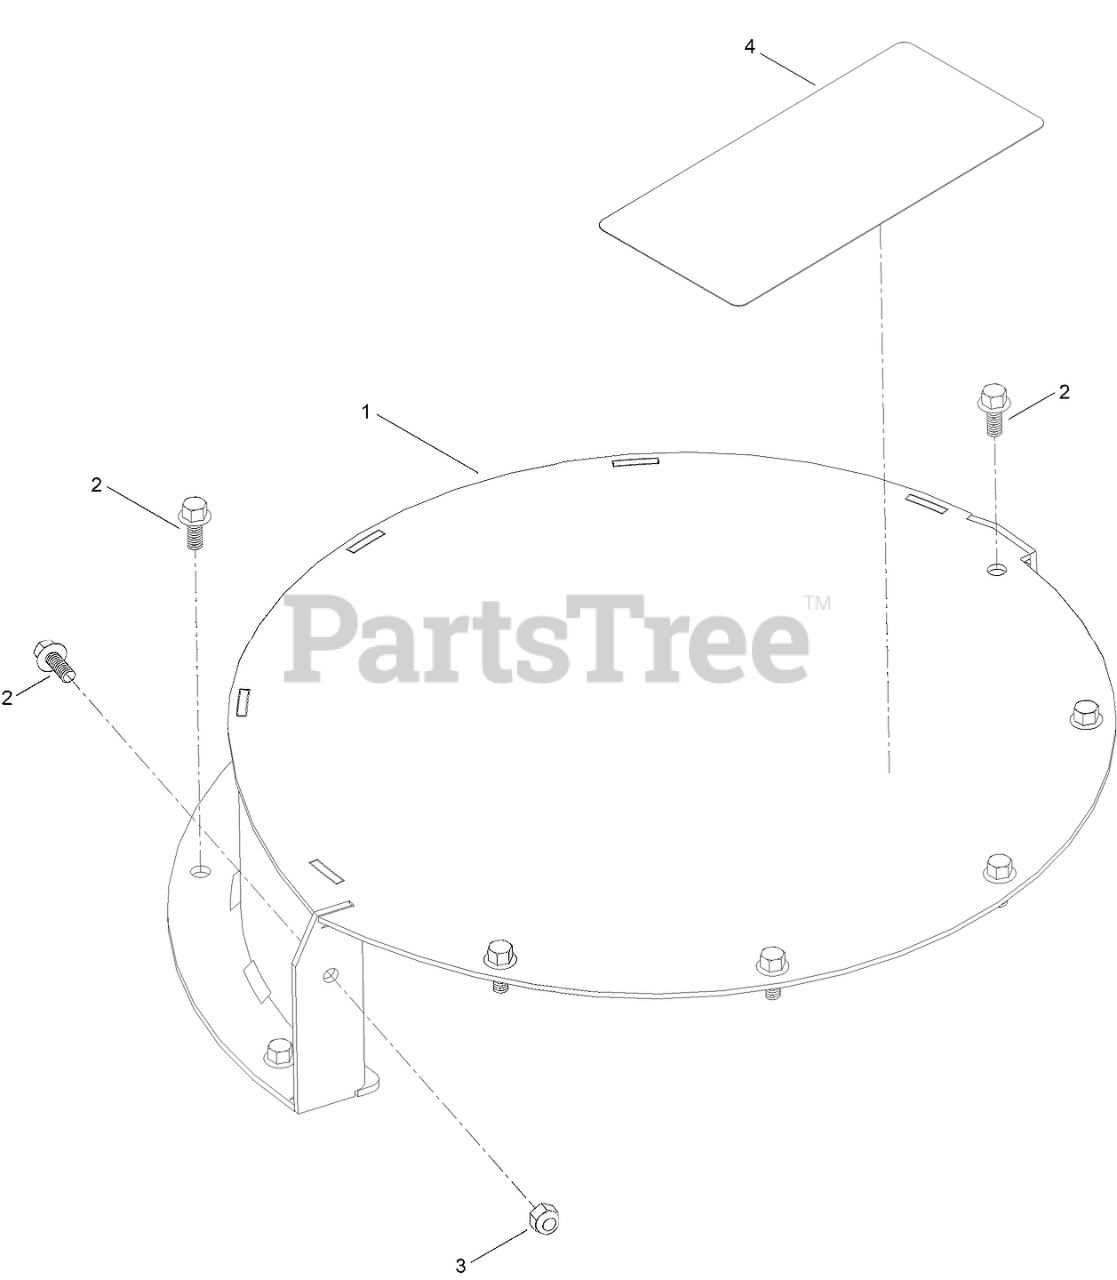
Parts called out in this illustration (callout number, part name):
1	UPPER HOUSING ASM
2	SCREW-HHF
3	NUT-HEX
4	DECAL-DANGER
